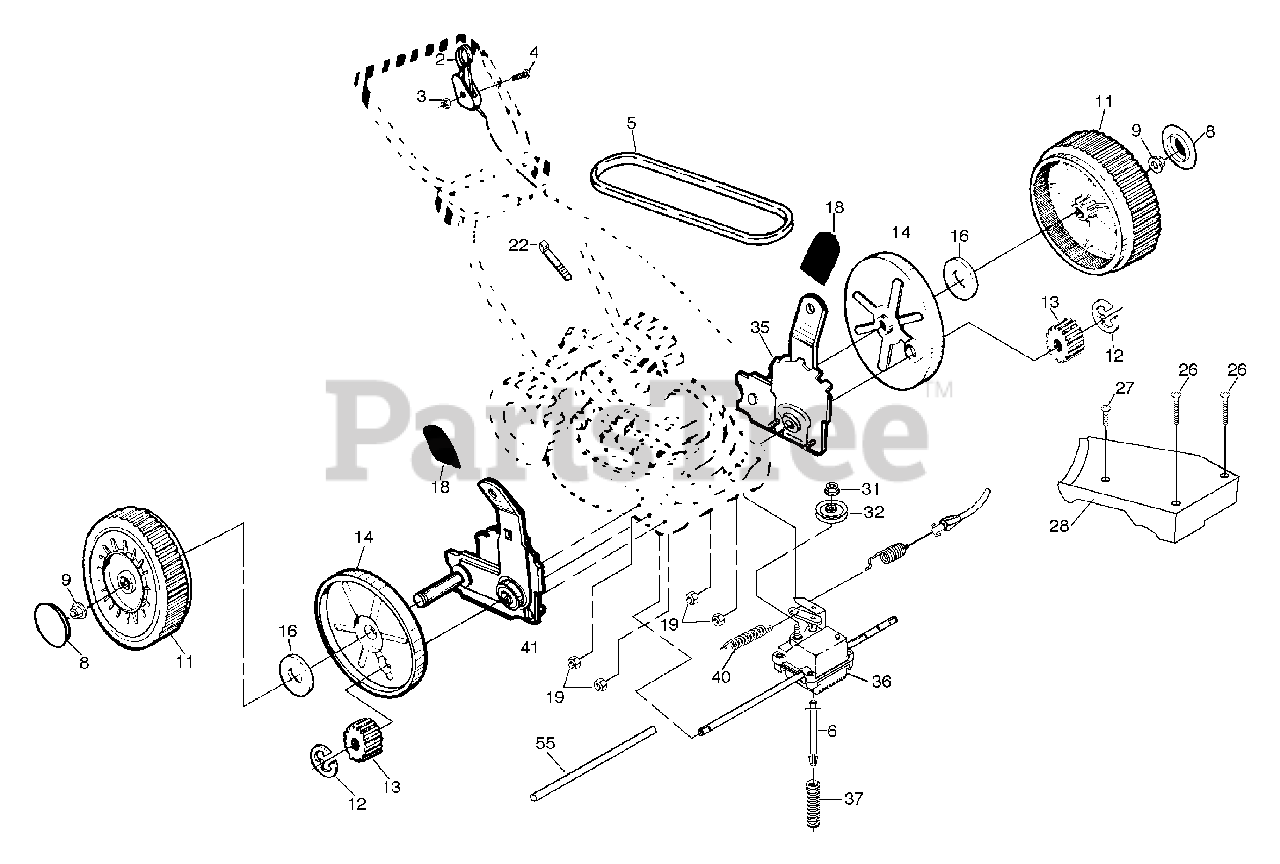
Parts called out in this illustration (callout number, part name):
2	Drive Control
3	Locknut #10-24
4	Hex Washer Head Screw 1/4-20 x 2.12
5	V-Belt
6	Spring Retainer
9	Flanged Locknut 3/8-16
11	Wheel & Tire Assembly
14	Dust Cover
16	Washer 1/2 x 1-1/2 x .134
18	Selector Knob
19	Hex Locknut 1/4-20
22	Wire Tie
26	Pan Head Tapping Screw #10-24 x 2-3/4
27	Hex Head Tapping Screw #10-2
28	Drive Cover
31	Hex Flange Nut
32	Drive Pulley
35	Wheel Adjuster Assembly (Left)
36	Gear Case Assembly
41	Wheel Adjuster Assembly (Right)
55	Driveshaft Cover
